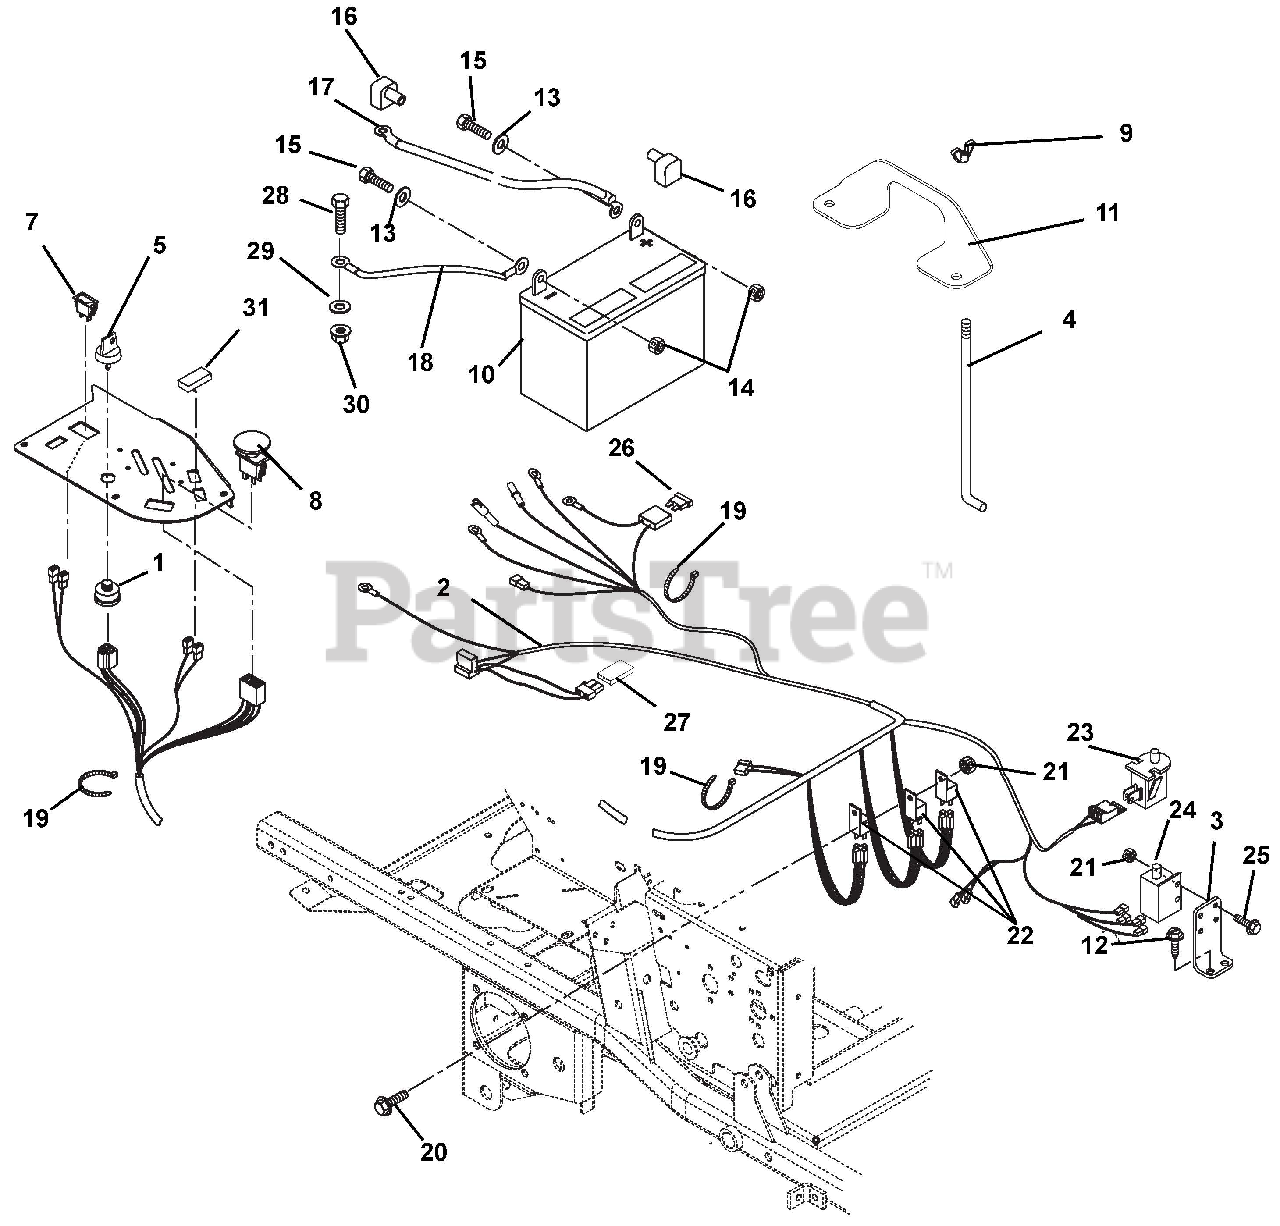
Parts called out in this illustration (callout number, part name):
1	Switch, Ignition
2	Harness, MZ Vertical A/C
2	Harness, MZ VERTICAL Liquid Cooled
3	Mount, Safety Switch
4	Rod, Battery Holddown .25 x 6.62
5	Key, with Shield
6	Ignition Key Set
7	Hour Meter
8	Switch, PTO Clutch
9	Nut, Locking Wing .25-20
10	Battery, 12V
11	Hold Down, Battery
12	Screw, Tapping .25-20 x .50 Hex Washer Head
13	Washer, Flat-Steel .281 x .620 x .065
14	Nut, Locking-Top-Flange .25-20
15	Bolt, Hex .25-20 x .75 Grade 5
16	Battery Terminal Boot, Red
17	Starter Cable 13 in.
18	Ground Cable
19	Cable Tie
20	Screw, Machine 10-24 x .50 Hex Washer Head
21	Nut, Locking-Nylon 10-24 With Insert
22	Relay
23	Switch, Snap Mounting
24	Switch, Double Pole N.O./N.O.
25	Screw, Machine 10-24 x .75 Hex Washer Head
26	Fuse, 30 Amp
27	Diode, Connector Shell
28	Bolt, Hex .31-18 x .75 Grade 5
29	Washer-Flat-Steel .344 x .688 x .065
30	Nut, Locking-Top-Flange .31-18
31	Light, Indicator
31	Switch, Blank
